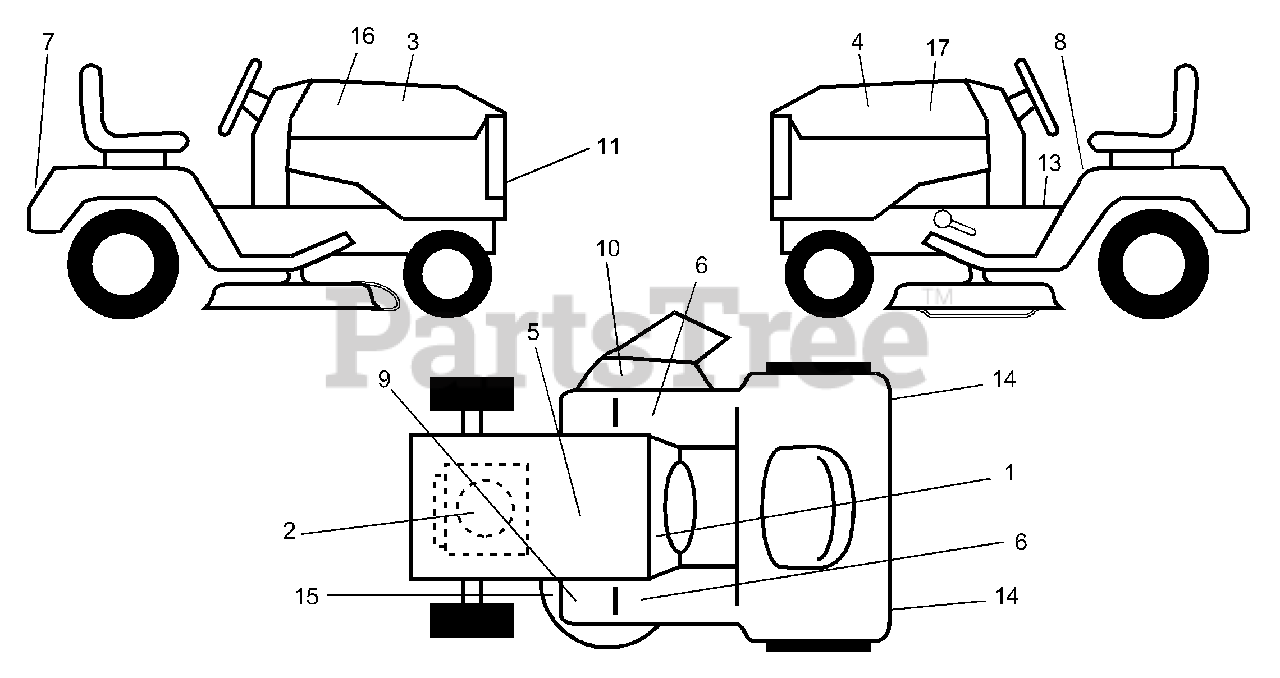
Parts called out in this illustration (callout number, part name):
1	Decal Instruction Dash Eng/fr
2	Decal HP Engine
3	Decal Hood RH Husq
4	Decal Hood LH Husq
5	Decal Caution Battery Fr/ger
6	Decal Pad Footrest Rbr Sq Generic
7	Decal Fender Husqvarna
8	Decal Caution Fender Eng/fr
9	Decal Clutch/brake Eng/fr
10	Decal Warning MULT-LANGUAGE
11	Decal Grille Husqvarna
13	Decal Brake Parking Saddle
14	Reflector Tail Light Red/amber
15	Decal V-Belt Mower Multi-Lang.
16	Decal Insert Hood Rh YT180 6 sp.
17	Decal Insert Hood Lh YT180 6sp.
